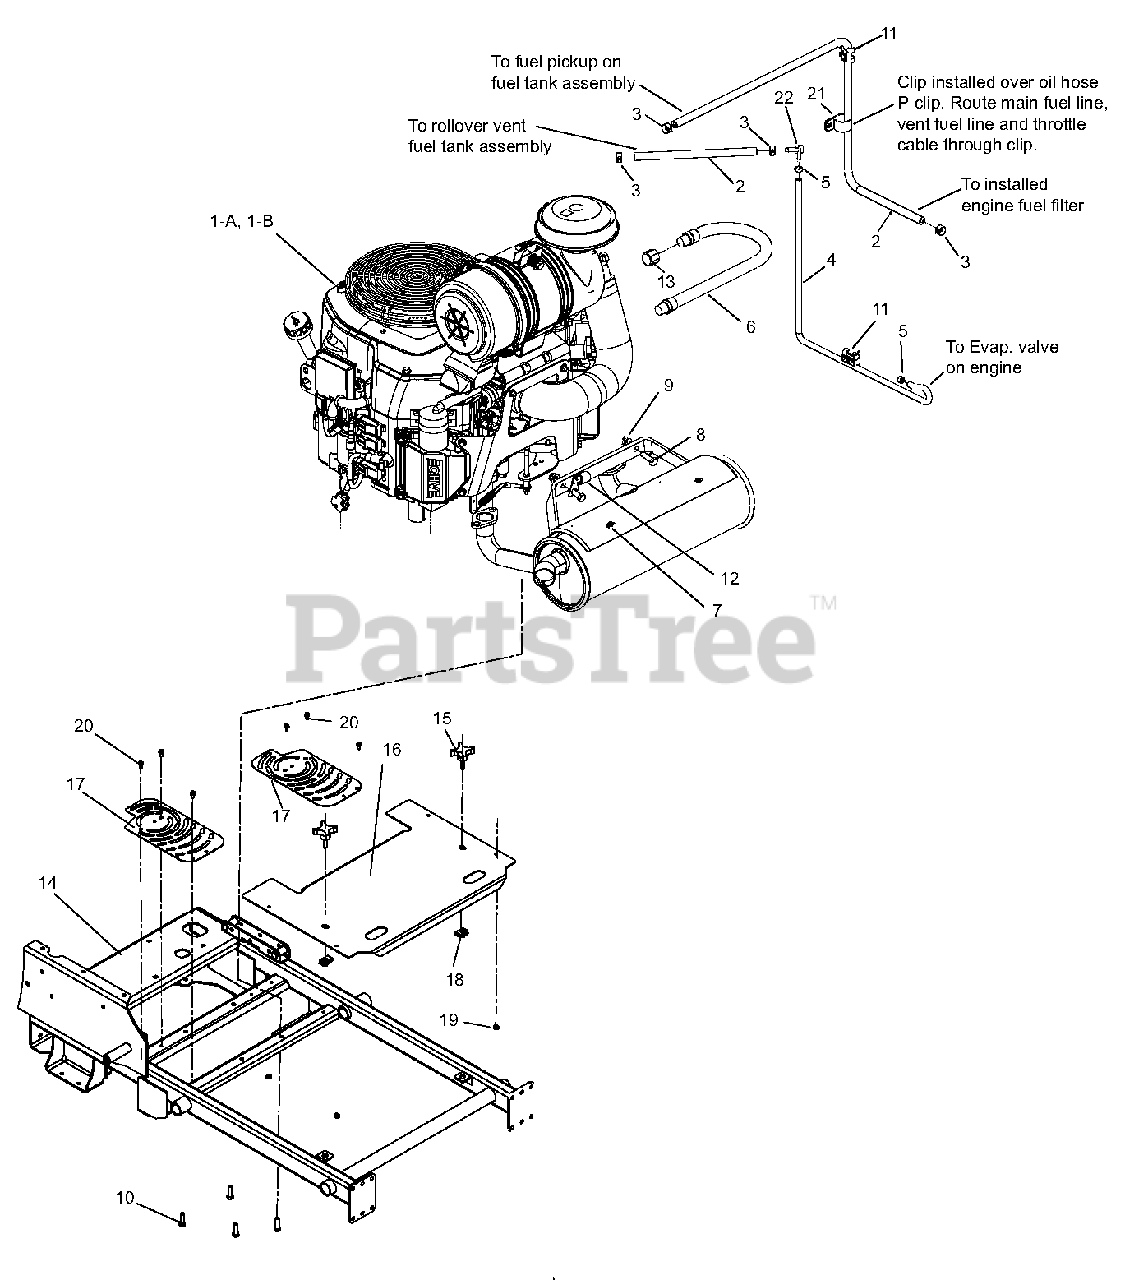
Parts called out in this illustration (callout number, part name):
1-A	ENGINE, 23 HP KOHLER EFI (994113)
1-B	ENGINE, 25 HP KOHLER EFI (994115)
2	HOSE, .25 LOW-PERM BULK GAS (24")
3	CLAMP, FUEL LINE
4	HOSE, .188 LOW-PERM BULK GAS (30")
5	CLAMP - HOSE, SPRING .188
6	HOSE, HYD .38-14 OK M6NO-M6NO (OIL DRAIN)
7	MFLR, KOHLER
8	BLT-HEX .31-18 X 1.00 GR5 YWZC
9	NUT-LK-NYL-FLG .31-18 YWZC
10	SCR-TAP .38-16 X 1.50 HWH TR YZ
11	CLIP, T .38-50
12	P-CLIP, .500 INSULATED
13	PIPE CAP 3/8 NPT FEMALE
14	WLDMT, FRAME PROSTANCE
15	KNOB, 3/8 X 1.25 - 4 PRONG
16	SHIELD, DECK
17	GUARD, FAN
18	NUT, RTNR .375-16 X .37
19	BUMPER GROMMET .125 X .25 REV
20	SCR-TAP .25-20 X .50 HWH TR YWZ
21	CLAMP, CUSHIONED STEEL
22	FITTING, 90 VACUUM 3/16 1/4
